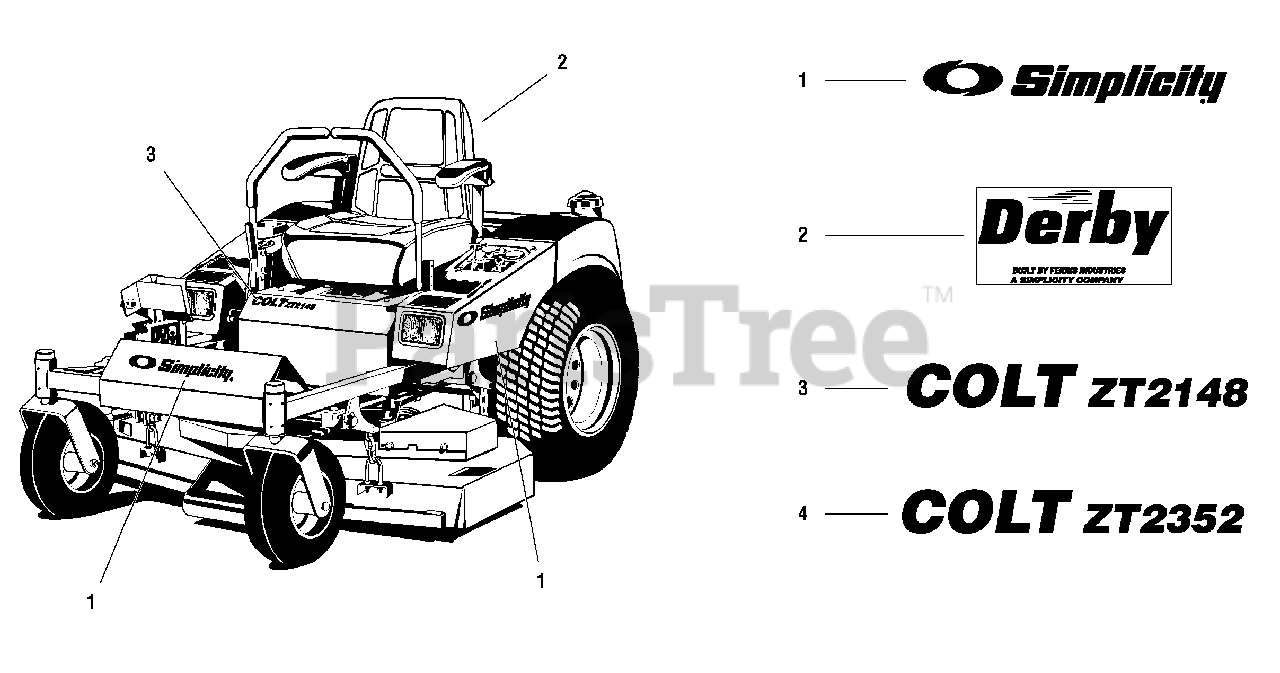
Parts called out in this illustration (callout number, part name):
1	DECAL, Simplicity Logo
2	DECAL, Derby Built By
3	DECAL, Colt ZT2148
4	DECAL, Colt ZT2352
